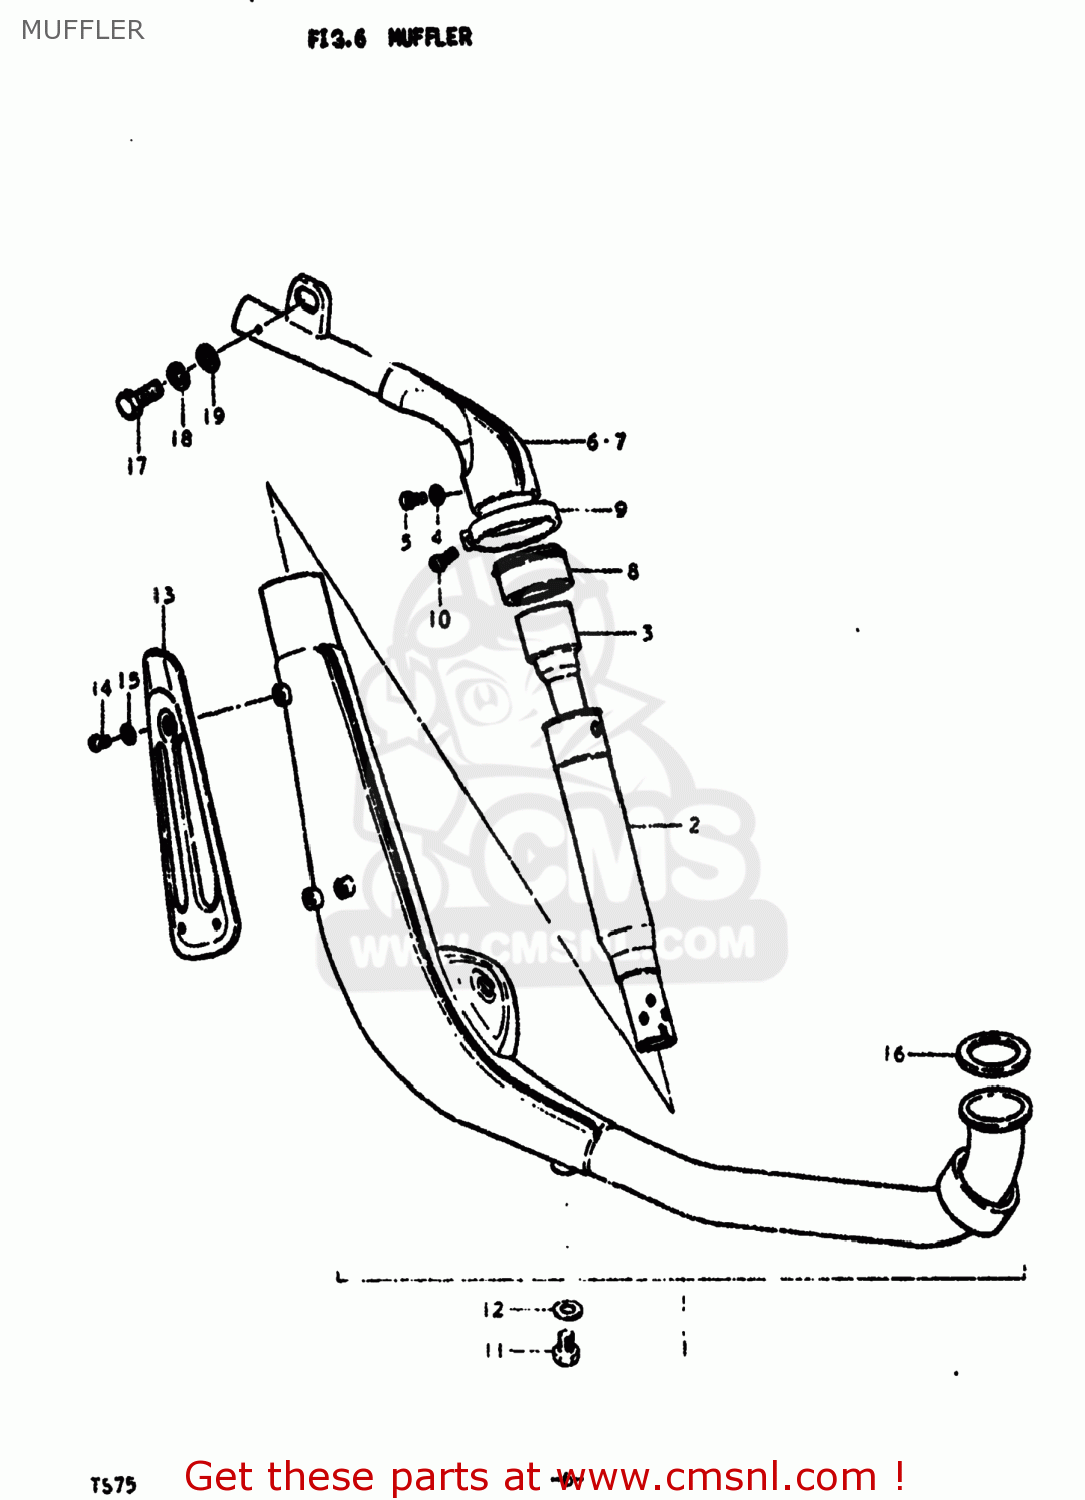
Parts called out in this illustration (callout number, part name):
1	MUFFLER ASSEMBLY
2	ARRESTER,SPARK
3	TUBE,MUFFLER CLEAN OUT
4	GASKET
5	SCREW(6X12)
6	EXHAUST EXTENSION
7	EXHAUST EXTENSION
8	GASKET,MUFFLER TAIL PIPE (NAS)
9	CLAMP
10	SCREW
11	BOLT 10X9
12	GASKET(10X14X3.6) (NAS)
13	COVER,MUFFLER
14	SCREW
15	LOCK WASHER
16	GASKET,EXHAUST PIPE (NAS)
17	BOLT 10X20
18	LOCK WASHER
19	WASHER
